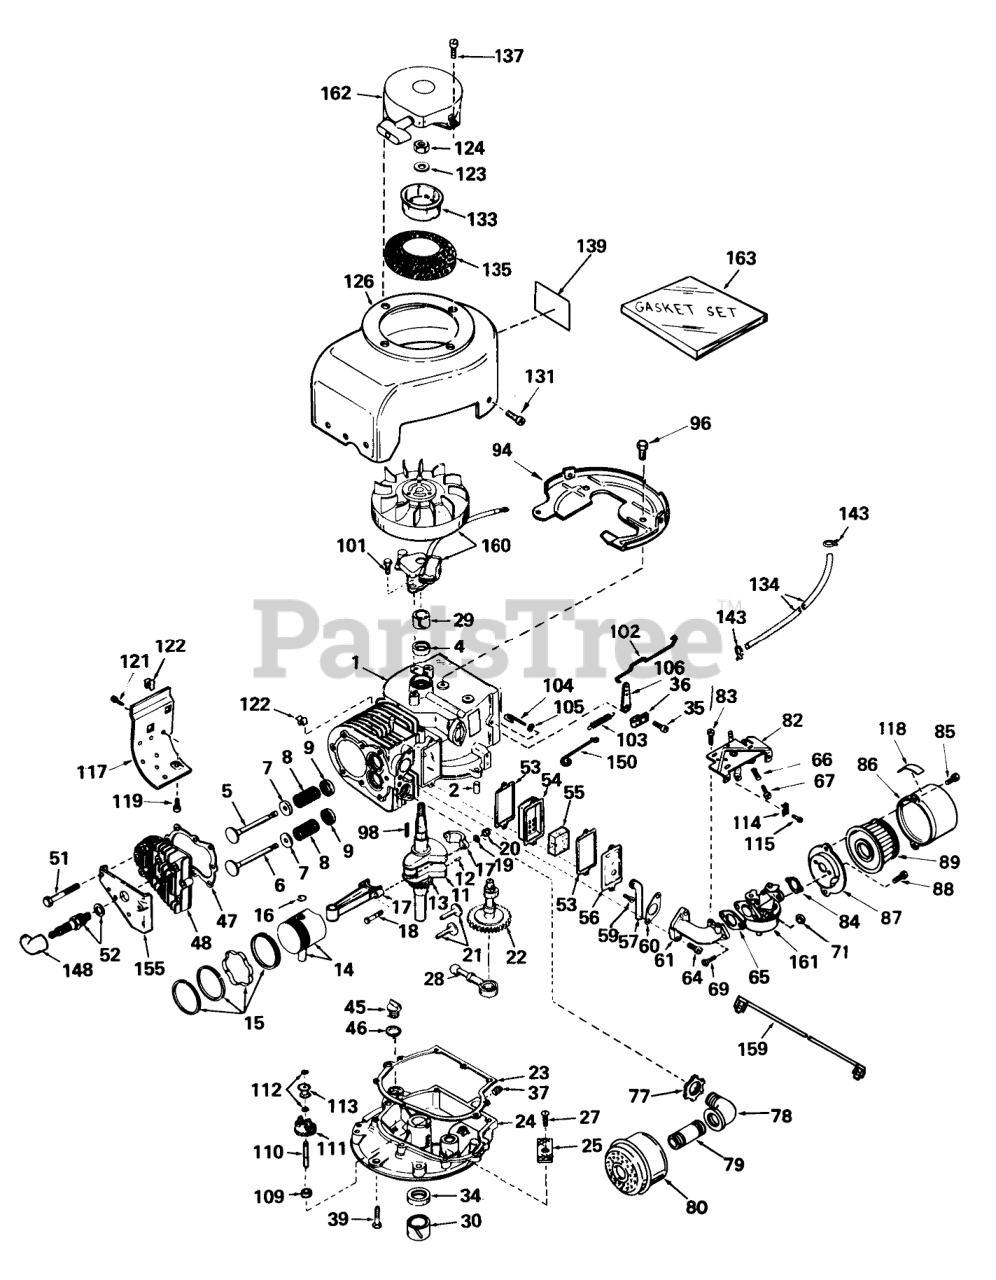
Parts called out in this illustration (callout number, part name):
1	Cylinder Assy.(Incl. Nos. 2 & 4)
2	Pin-Dowel
4	Seal, Oil
5	VALVE, INTAKE (STANDARD)
5	VALVE, INTAKE (1/32" OVERSIZE)
6	VALVE, EXHAUST (STANDARD)
6	VALVE, EXHAUST (1/32" OVERSIZE)
7	Cap-Spring, Valve
8	Spring-Valve
9	Keeper-Spring, Valve
11	Crankshaft Assy. (Incl. Nos. 12 & 13) V50-60126G
11	Crankshaft Assy. (Incl. Nos. 12 & 13) V50-60127G
12	Pin, Groove
13	Gear-Crankshaft
14	Piston & Pin Assy., Std., (Incl. 2 of No. 16)
14	Piston & Pin Assy. (.010 oversize)(Inc. 2 of No. 16)
14	Piston & Pin Assy. (.020 oversize)(Incl. 2 of No. 16)
15	Ring Set, Piston (Standard)
15	Bearing-Wrist Pin
15	Bearing-Crankshaft
16	Ring-Retaining, Piston Pin
17	Rod Assy., Connecting (Incl. Nos. 18, 19 & 20)
18	Bolt, Connecting Rod
21	Lifter Valve
22	Camshaft (Compression Release)
23	Gasket-Cover, Cylinder
24	Flange Assy., Mounting (Incl. Nos. 25, 27, 34, 45 & 110)
25	Screen-Oil Filter
28	Pump, Oil
29	Bushing, Crankshaft
30	Bushing, Crankshaft
34	Seal-Oil
35	Screw
36	Clamp-Lever, Governor
37	Plug-Drain, Oil (SQH 1/4-18)
39	Screw (1/4-20 x 1-1/4)
45	Plug-Fill, Oil
47	Gasket-Head, Cylinder
48	CYLINDER HEAD
51	Screw Hex Hd. Cap
52	Plug, Spark (J17LM or equiv.)
53	Gasket-Breather
54	Body-Breather
55	Element-Breather
56	Cover-Valve
57	Tube-Breather
60	Gasket-Intake
61	Pipe, Intake
64	Screw (T-30, 5/16-18x1-3/32)
66	Spring-Compression
67	Screw
69	Screw (1/4-28 x 7/8)
71	Nut and Lock Washer (1/4-28)
77	Nut, Conduit
78	Elbow, Exhaust (90 degree)
79	Nipple, Pipe
80	Muffler
82	Depth Bar
83	Screw (10-24 x 9/16)
84	Gasket
86	Body
87	Bracket
88	Screw (10-32 x 1/2)
89	Element
94	Baffle Blower Housing
96	Screw (1/4-20x19/32)
98	Key, Flywheel
102	Link Governor
103	Spring Governor
104	Rod-Governor (Incl. #5)
105	Washer-Flat
106	Lever-Governor
109	Spacer
110	Shaft, Governor
111	Governor Gear ASM
112	Ring-Retaining
113	Spool-Governor
114	Conduit
115	Screw (10-32 x 3/8)
117	Emnsion, Blower Housing
121	Screw
122	51004 GIL ROTARY TI
123	Washer
126	Housing, Blower
131	Screw, Hex Hd.
133	Cup-Starter
134	Line-Fuel
135	Screen, Air
139	480B GIL SNWTHWR O/
143	Clamp-Line, Fuel
148	Cover-Spark Plug
150	Link Governor Spring
155	Cover-Head, Cylinder
159	Wire, Ground
161	Carburetor
162	Starter, Rewind
163	Gasket Set
